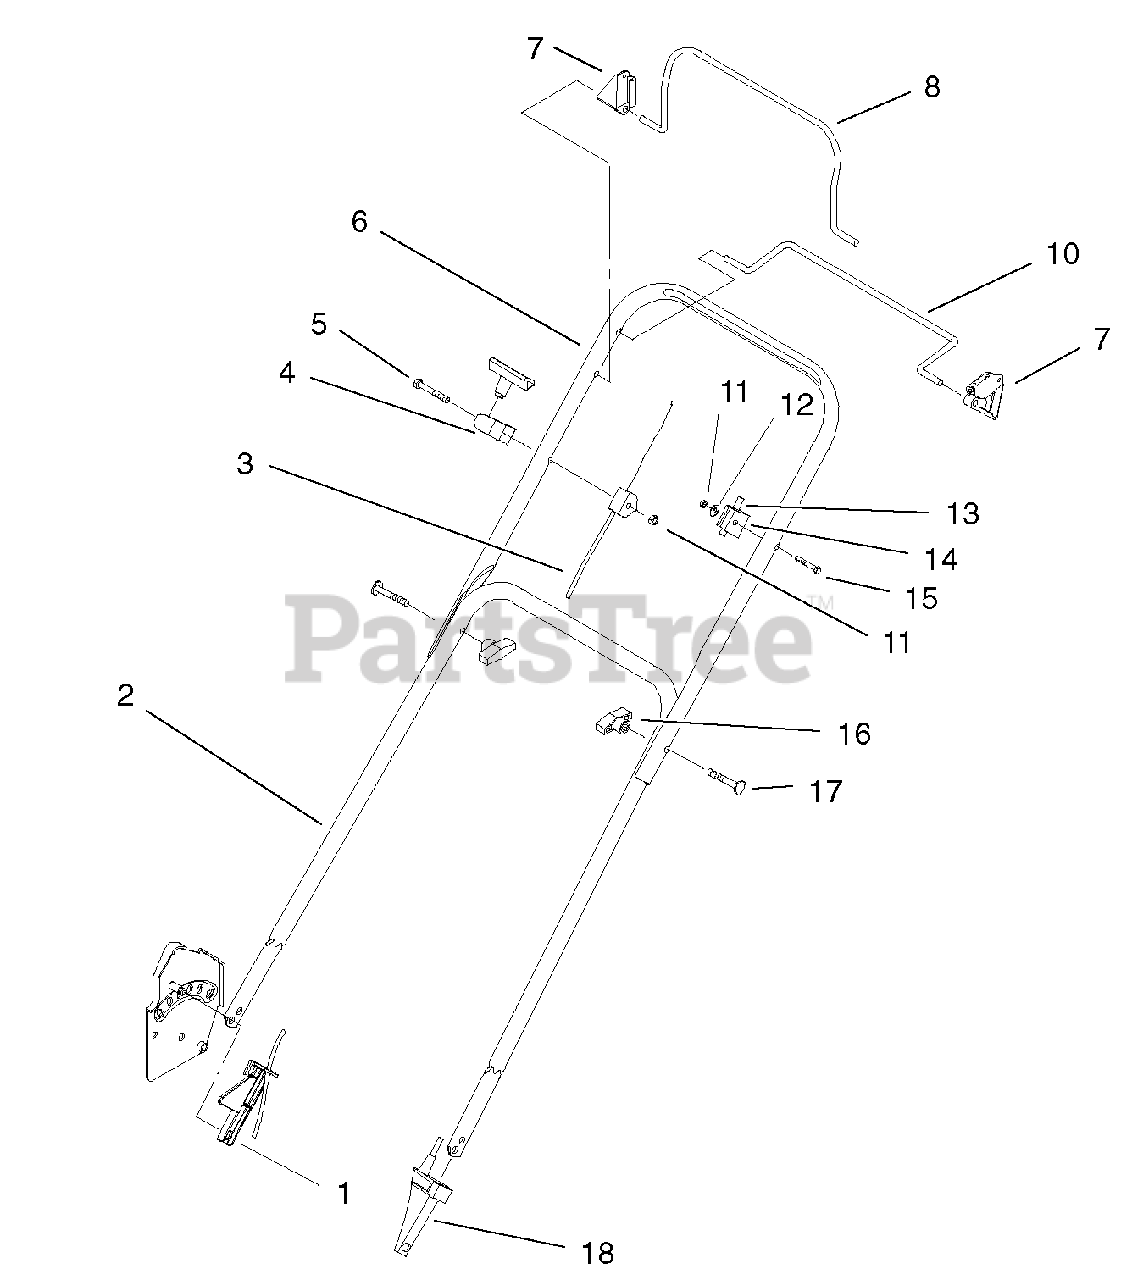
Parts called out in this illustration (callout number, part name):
1	Guard-Cable
2	Handle-Lower
3	Brake Cable ASM
4	Guide-Rope
5	Screw-HH
6	Handle-Upper
7	Stop-Pivot
8	Bail-Brake
10	Bail-Control
11	Nut-Lock, NI
12	Washer-Flat
13	Cable-Ground Speed
14	Anchor-Upper, Cable
15	Screw-Handle
16	Knob-Handle
18	Anchor-Cable
